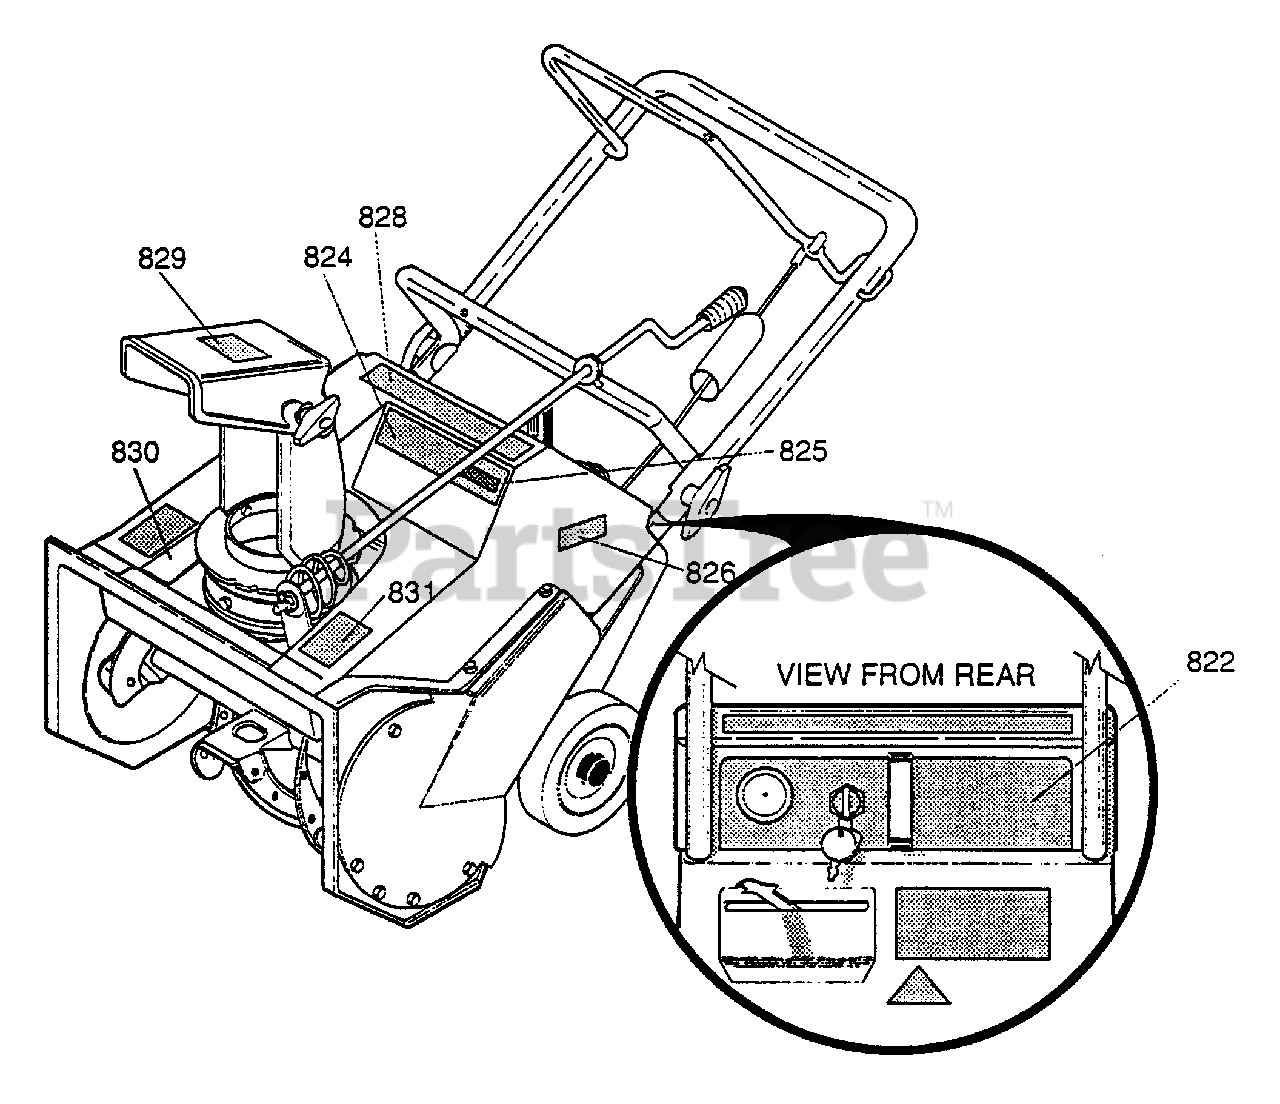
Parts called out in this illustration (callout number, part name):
822	DECAL, CNTRL PANEL
826	DECAL, DANGER MUFFLER
828	DECAL, START INSTR
829	DECAL, DANGER CHUTE
830	DECAL, DANGER CHUTE
831	DECAL, DANGER AUGER
